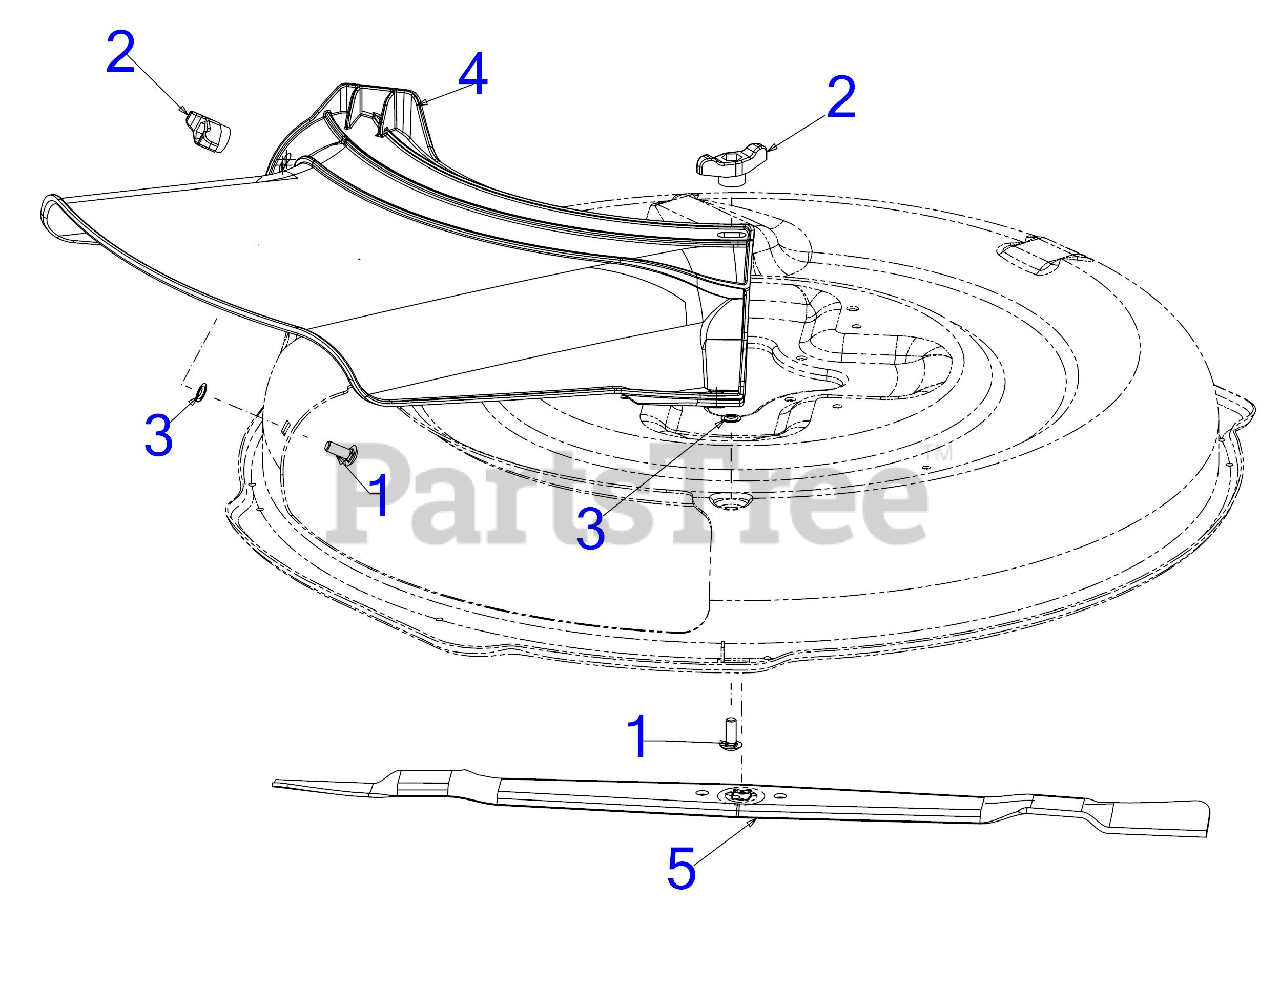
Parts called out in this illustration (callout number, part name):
1	BOLT 5/16-18X .875 GR1
2	WING KNOB 5/16-18
4	DEFLECTOR CHUTE
5	30" BLADE 3n1
